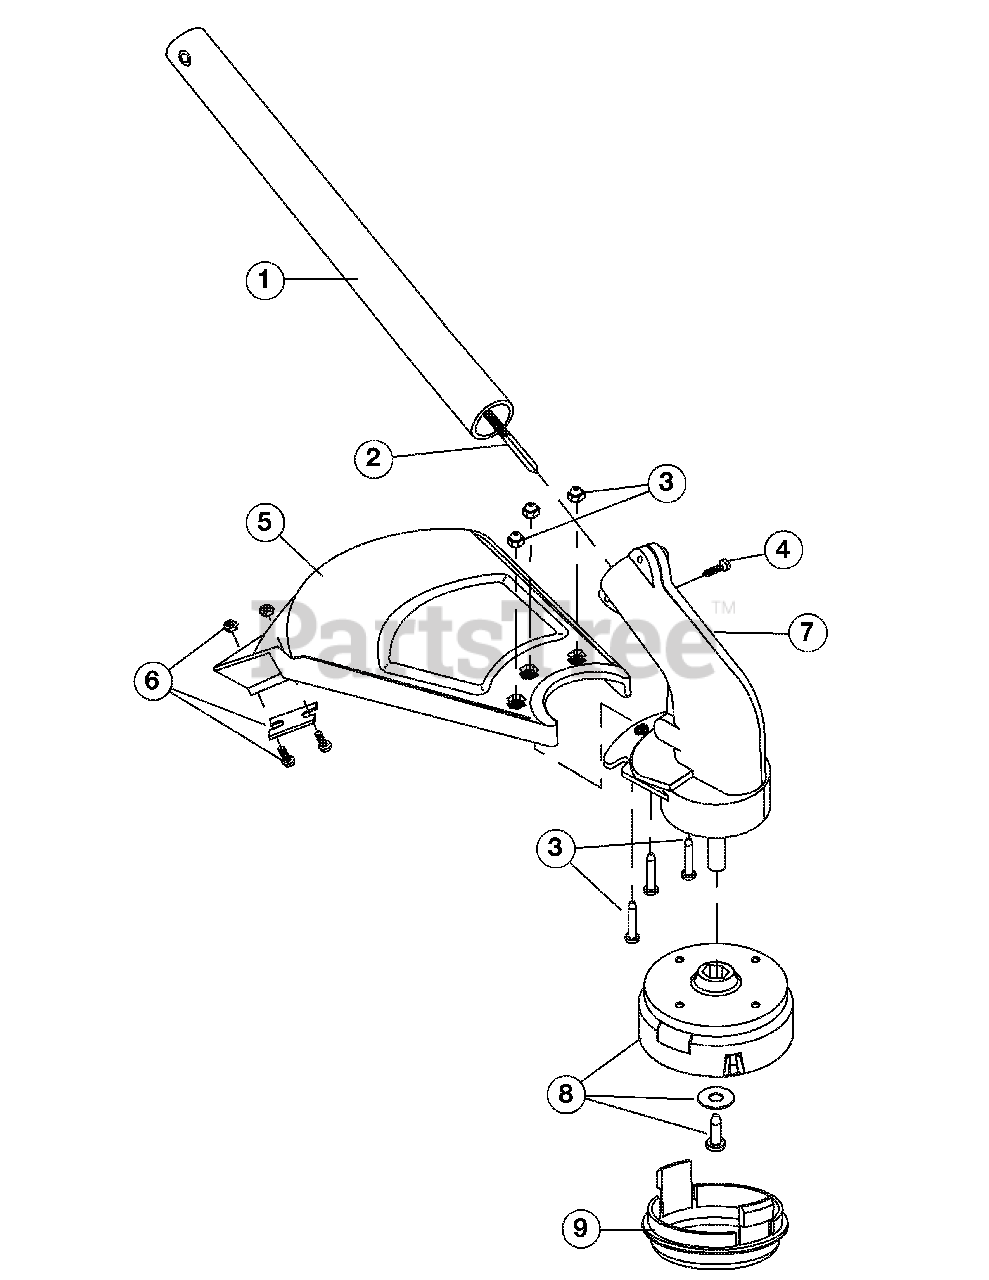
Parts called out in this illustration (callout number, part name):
1	Drive Shaft Housing Assembly
2	Flexible Drive Shaft
3	Guard Mounting Assembly
4	Anti-Rotation Screw
5	Guard & Blade Assembly
6	Blade Asssembly
7	Gearbox Assembly
8	Cutting Head
